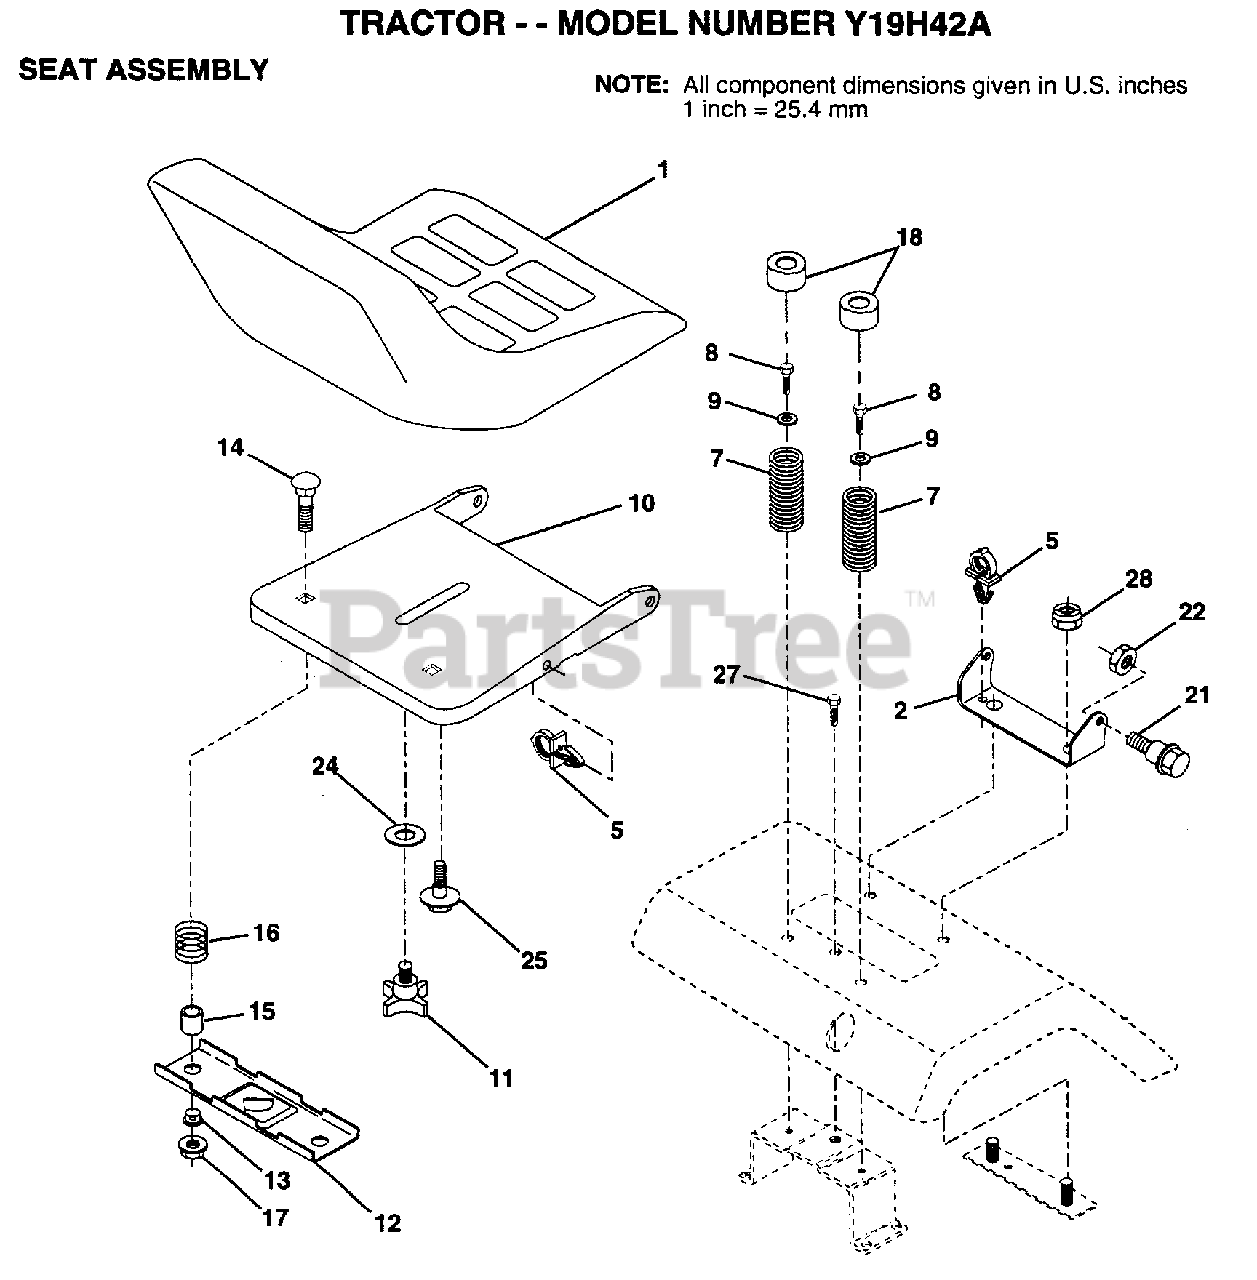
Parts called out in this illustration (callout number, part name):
2	BRACKET PVT SEAT
5	CLIP.PUSH-IN.HING
7	SPRING COMPRESSIO
8	SCREW LT
9	WASHER
12	BRKT SWITCH
13	BUSHING
15	SPACER SPLIT
16	SPRING COMPRESSED
17	NUT.LOCK.1/4.LGE.FLG.GR.5
18	CAP SPRING
21	BOLT.SHLD.5/16-18
24	WASHER
25	BOLT,SHOULDER
27	SCREW LT
